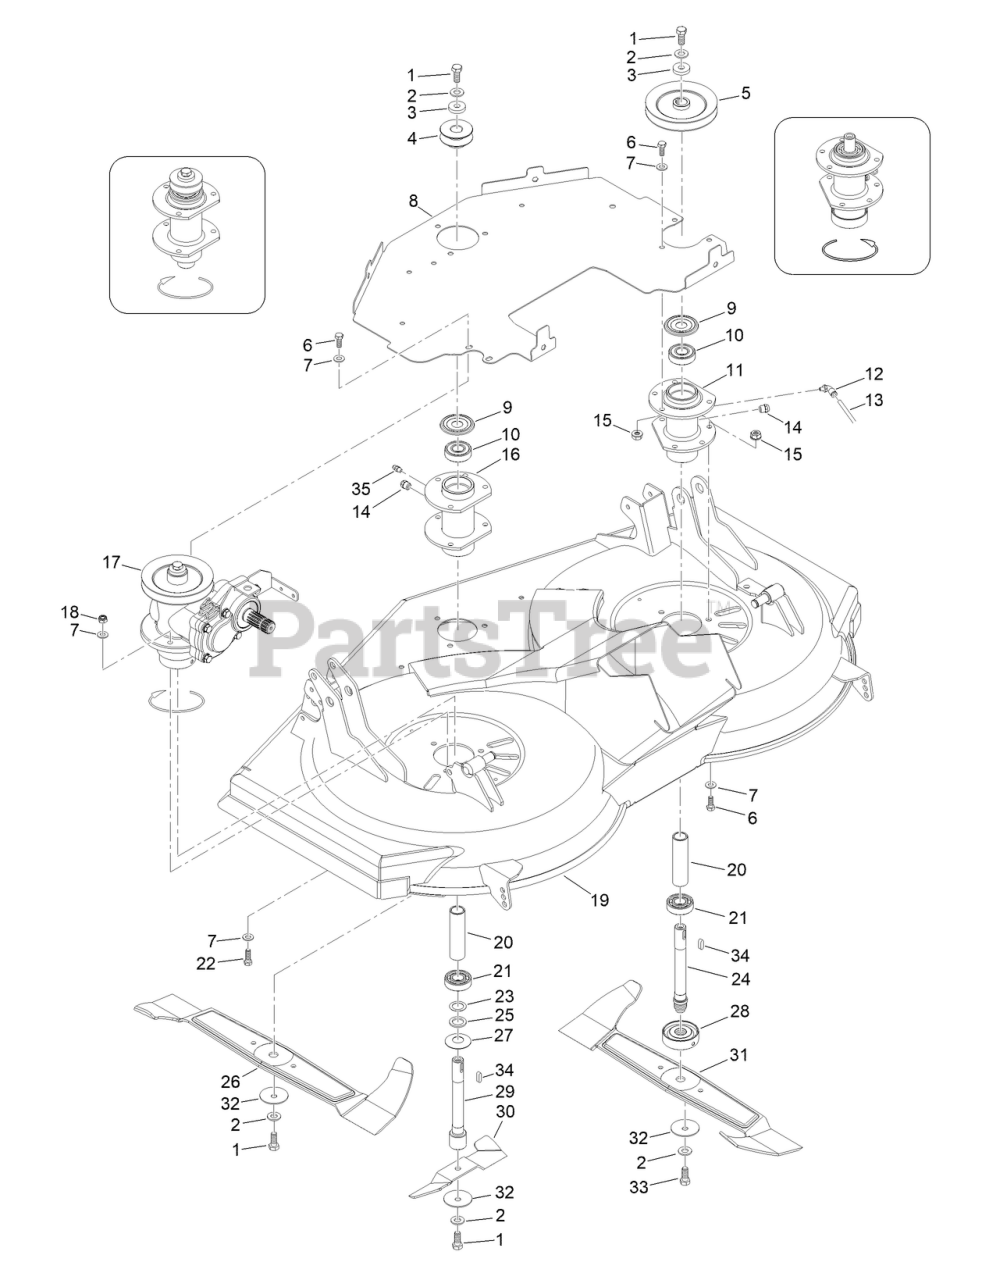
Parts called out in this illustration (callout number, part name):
2	WASHER
3	WASHER
4	PULLEY, CENTRAL BLADE
5	PULLEY, BLADE SHAFT
7	WASHER
8	SHELL, DECK
9	GUARD, PULLEY SIDE
10	BEARING, 6204 2RS
11	HUB, RIGHT BLADE
12	FITTING, TAPER
14	PURGE VALVE
16	HUB, CENTRAL BLADE
17	DECK GEARBOX ASSY
19	DECK, CHASSIS
20	SPACER, HUB
21	BEARING, 6204 RS
23	SPACER
24	SHAFT, RIGHT BLADE
26	BLADE-ROTARY, LH
27	GUARD, BLADE SIDE
28	SUPPORT, BLADE
29	SHAFT, CENTRAL BLADE
30	BLADE-ROTARY, CENTER
31	BLADE-ROTARY, RH
32	WASHER, BELLEVILLE
33	SCREW-HH, LH THD
35	FITTING-GREASE
